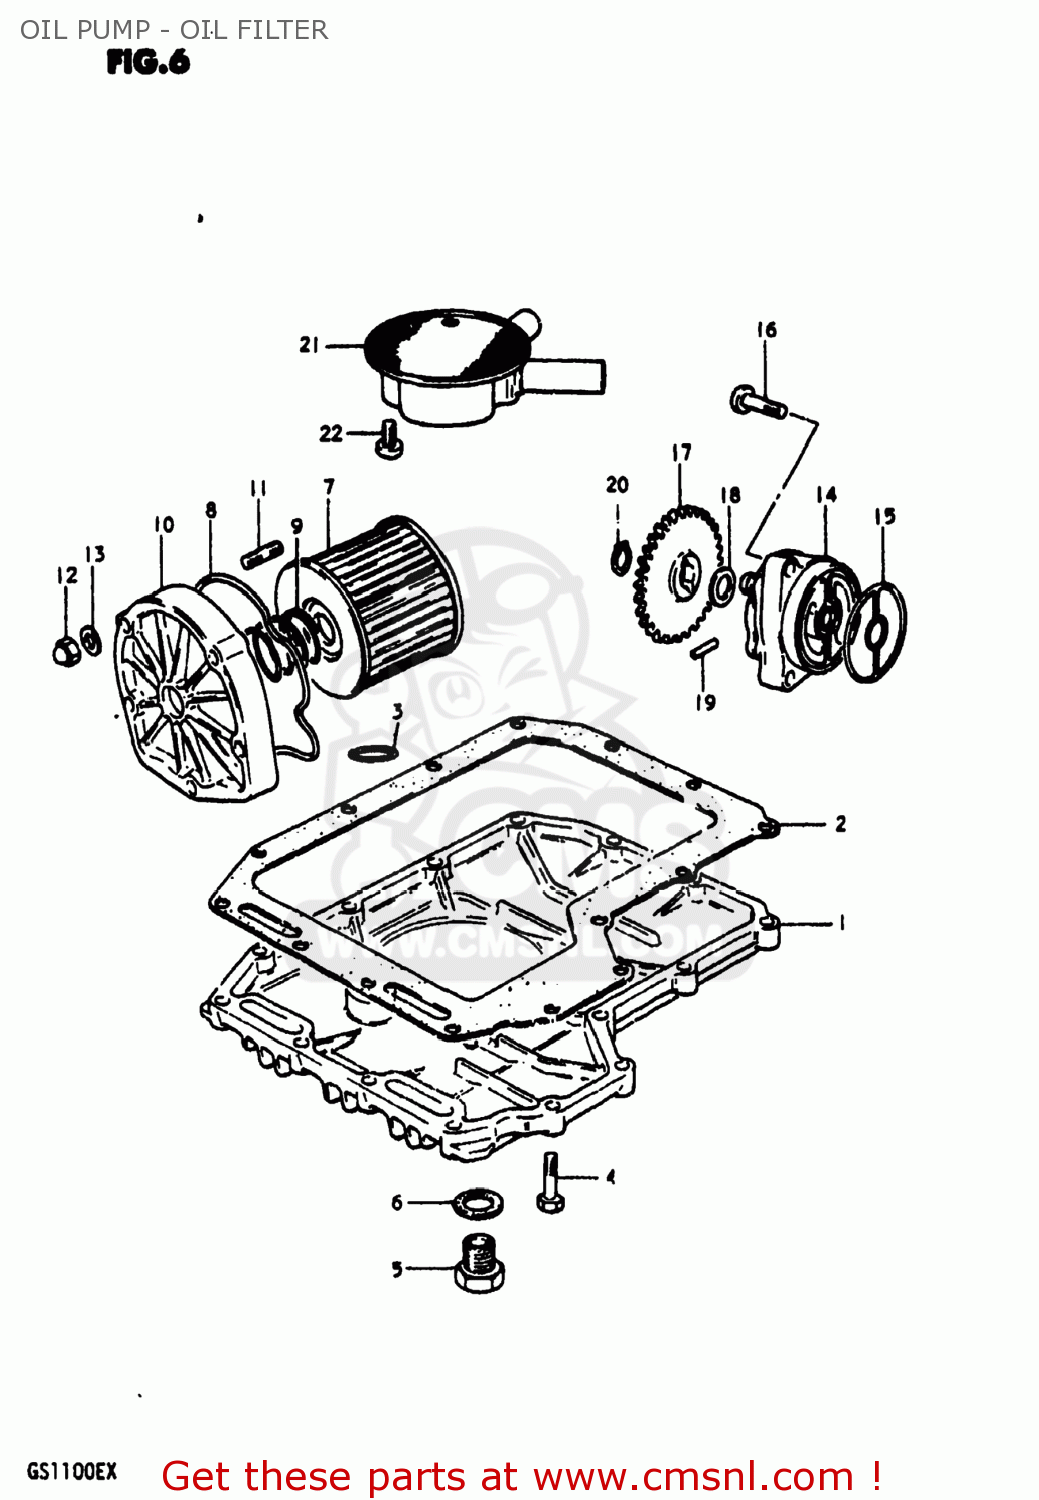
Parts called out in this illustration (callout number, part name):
1	PAN,OIL
2	GASKET,OIL PAN (MCA)
3	O RING(D:3.2,ID:12.9)
4	BOLT
5	PLUG
6	GASKET(14X19.2X2) (NAS)
7	FILTER ASSY,ENGINE OIL
8	O RING,OIL FILTER CHAMBER CAP
9	SPRING
10	CAP,ENG OIL FLTR OUTER CHAMBER
11	STUD 6X25
12	NUT
13	WASHER
14	PUMP ASSEMBLY,OIL
15	O-RING,OIL PUMP
16	SCREW
17	GEAR,OIL PUMP DRIVEN
18	SHIM
19	PIN(4X15.8)
20	CIRCLIP
21	STRAINER,ENGINE OIL
22	SCREW 6X12
